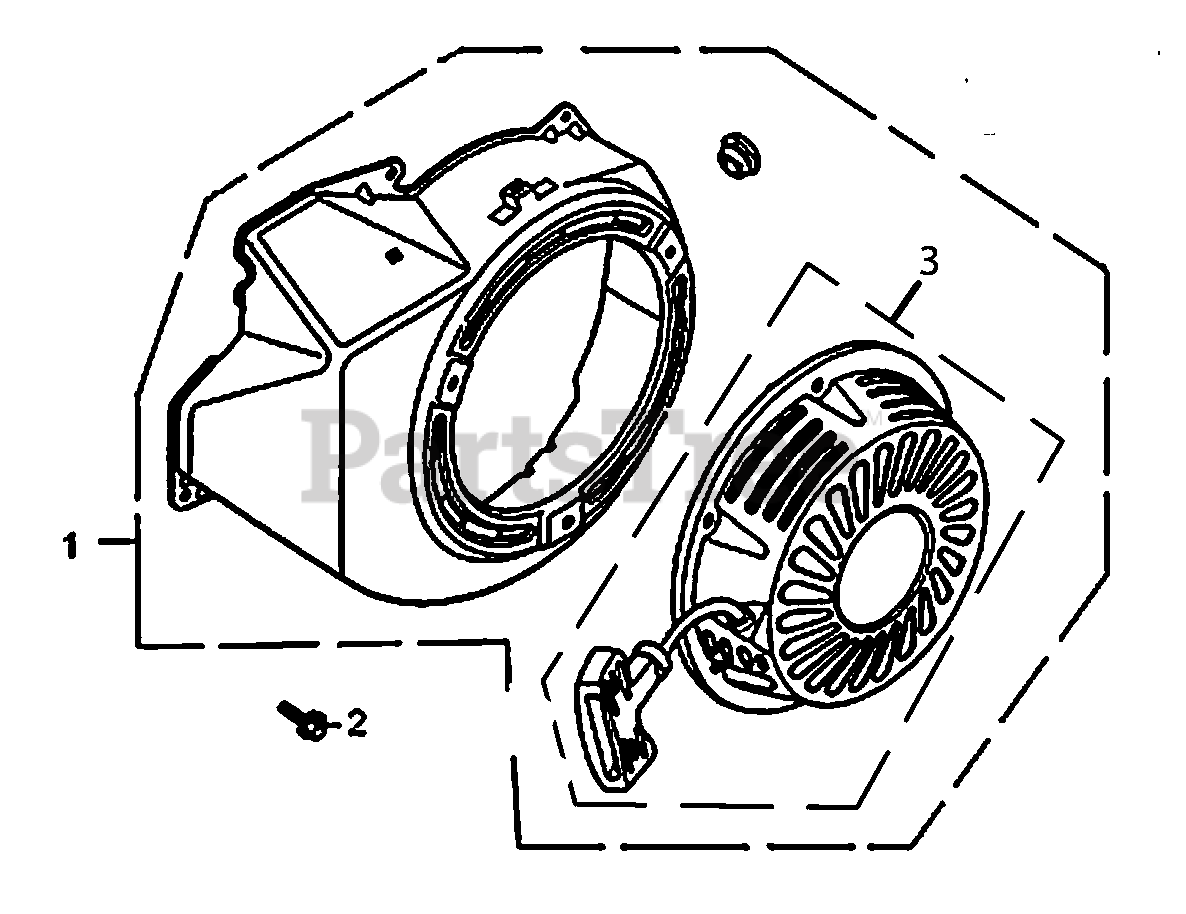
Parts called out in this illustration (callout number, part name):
1	STARTER ASSY. HW
2	BOLT' FLANGE' M6 X12
3	ASSY' RECOIL STARTER HW (W/O BLOWER HOUSING)
